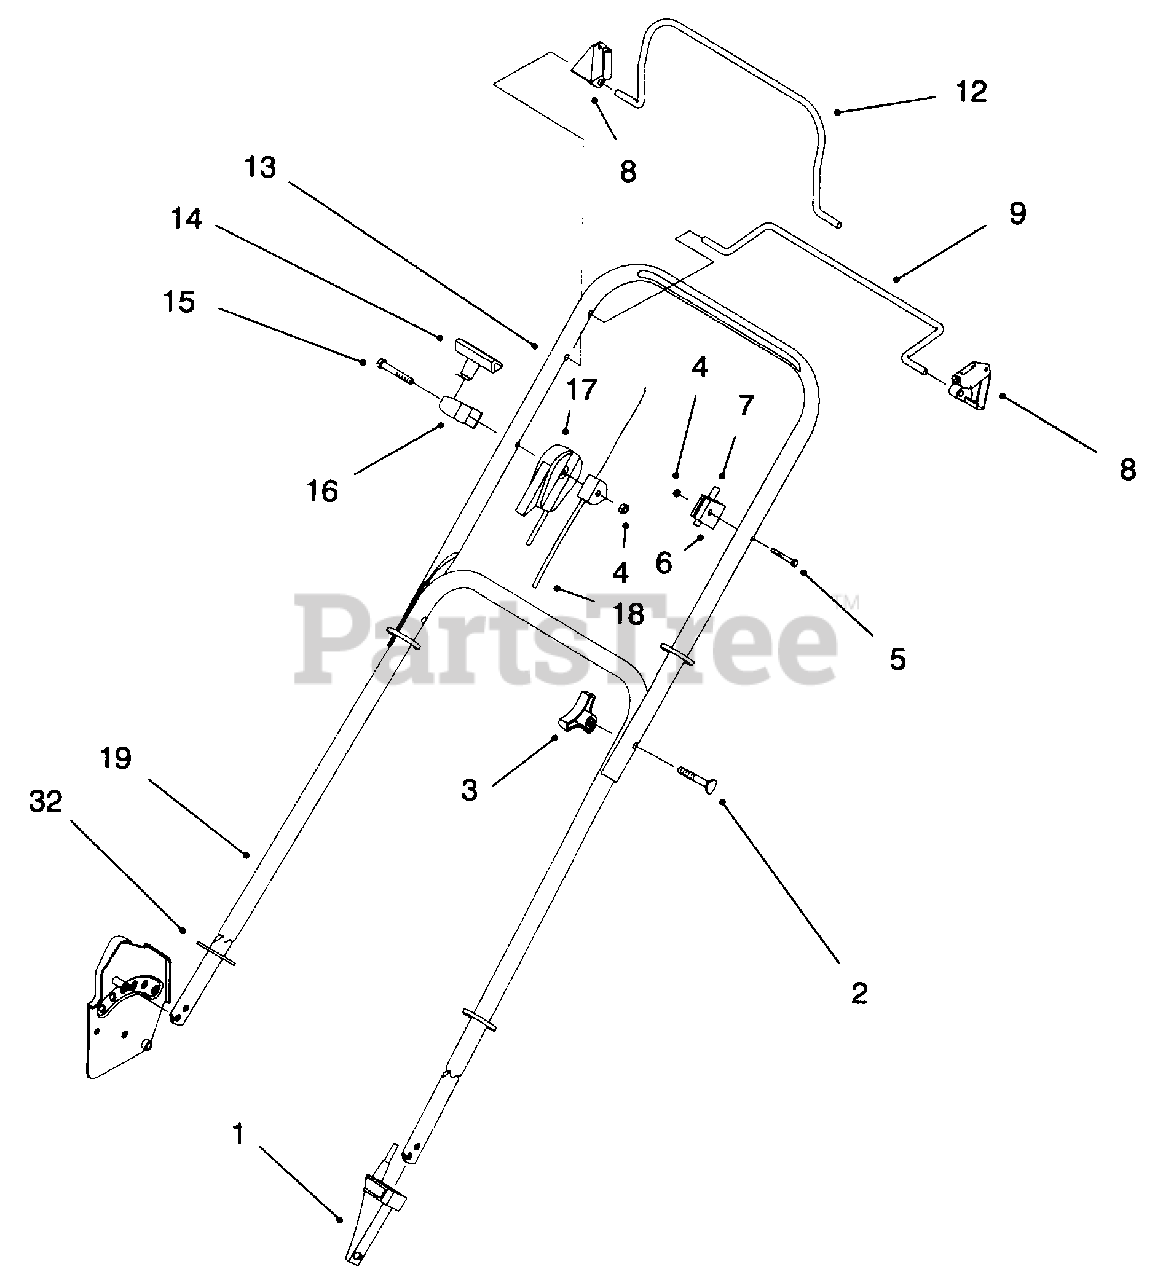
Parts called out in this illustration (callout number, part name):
1	Anchor-Cable SP Lower
2	Screw-Handle
3	Knob
4	Nut-Lock
5	Screw-Handle
6	Anchor-Cable SP Upper
7	Cable-Traction
8	Stop-Pivot
9	Bail-SP Control
12	Bail-Flywheel Brake
13	Handle-Upper
14	Handle-Starter
15	Screw-Hex Hd. Cap
16	Guide-Rope
17	Cable-Throttle
18	Cable-Brake Assembly
19	Handle-Lower
32	Guard-Handle
